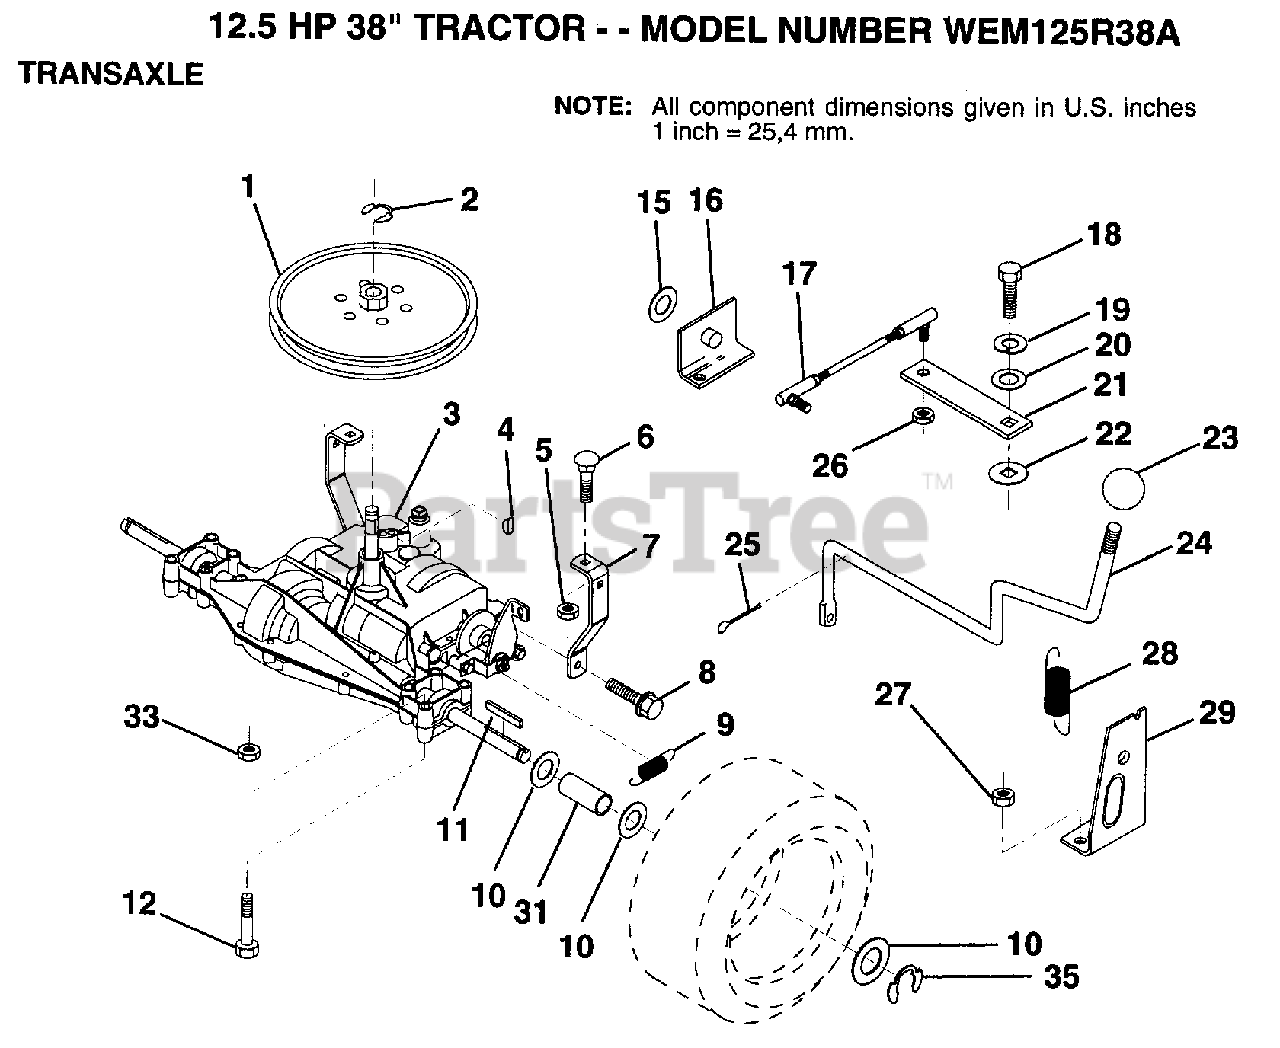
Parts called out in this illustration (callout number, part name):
1	PULLEY
5	NUT
6	BOLT
7	"STRAP,TORQUE"
8	SCREW
10	WASHER
11	SQUARE KEY
12	BOLT
16	"SUPT,HDLE SHT LH"
17	"LINK,SHIFT"
19	LOCKWASHER
20	WASHER LT
21	"ARM,SHIFT"
22	WASH-SHFT PLT LT
23	KNOB.DUCKHEAD.1/2
24	"ROD,SHIFT"
25	PIN COTTER 1/8
26	NUT.LOCK.5/16-24
28	"SPRING,EXT"
29	"SUPT,HDLE RH"
31	SPACER LT
33	NUT
35	E-RING LT
